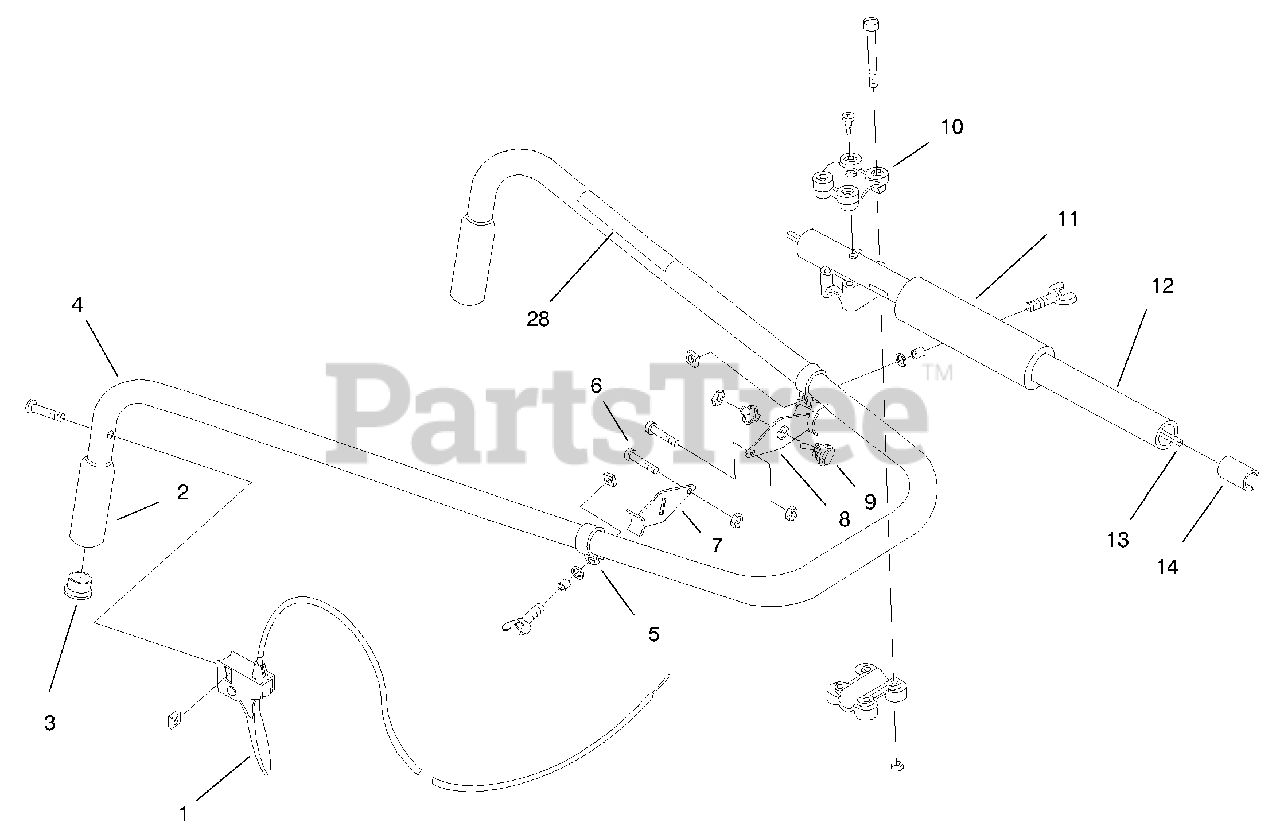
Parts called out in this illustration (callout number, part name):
1	Throttle Asm.
3	Tube Closure
4	Handle Bar
5	Clamp Asm.
6	Engine Bracket Mounting Hardware
7	Engine Mount Bracket, R.H.
8	Engine Mount Bracket, L.H.
9	Switch Asm.
10	Handle Bracket Asm.
12	Drive Shaft Housing Asm.
13	Flexible Drive Shaft
14	Retainer Sleeve
28	Decal-Safety Symbols
